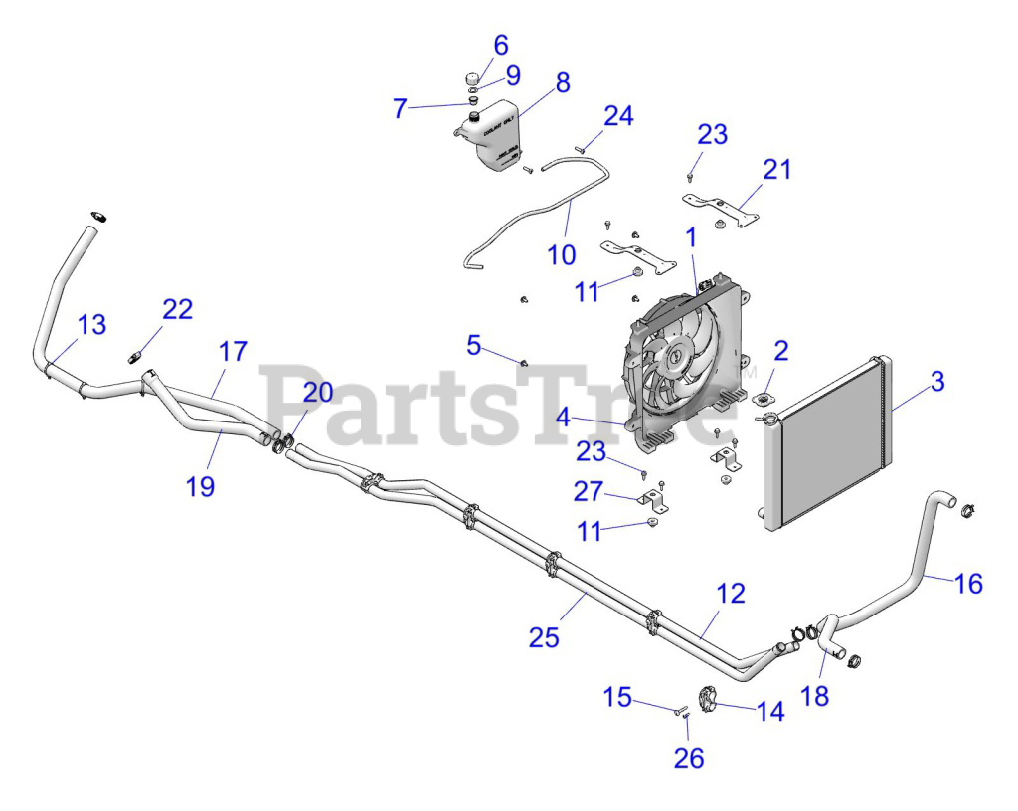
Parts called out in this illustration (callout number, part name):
1	ASM-RADIATOR
3	ASM-RADIATOR- CORE
4	ASM-FAN-RADIATOR
5	BOLT-M6X15MM
6	CAP- OVERFLOW
7	CAP-PLUG9X(GRN)-FLEX TEMP(10)
8	TANK-SURGE
9	GASKET (10)
10	FUEL LINE-95 CENTIMETERS
12	TUBE-COOLANT
13	CLIP-ROUTING
14	CLIP-COOLANT ROUTING
15	SCR-M6X1X40-TR/TX-BLK
16	HOSE-UPPER- RAD
17	HOSE-ENGINE,OUT,GAS
18	HOSE-LOWER- RAD
19	HOSE-ENGINE,IN
20	CLAMP-SPRINGBAND 35/12-BLK
21	BRKT-MOUNT-RADIATOR-ARNS-BLK
22	CLAMP-HOSE(WORM DR)25-40MM
23	SCR-M6X1.0X20-HXHD-FLG-TDFM-BL
24	SCR-#14X1 HI/LO-PH-PN TRX-M
25	TUBE-COOLANT
27	BRKT-RADIATOR MNT-LWR-BLK
